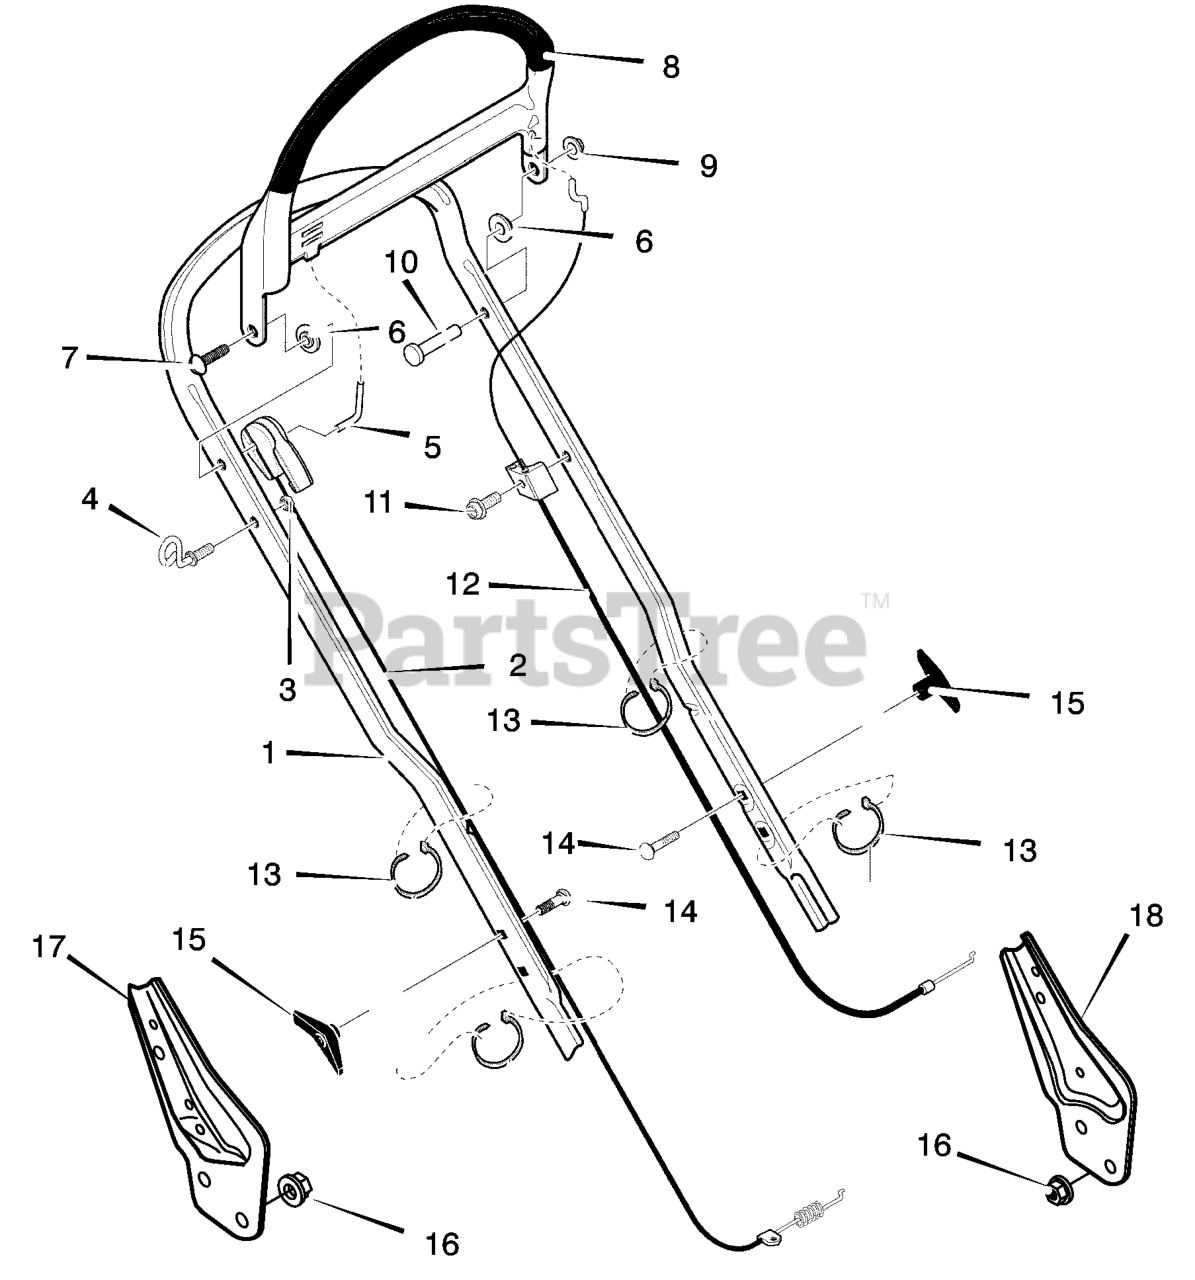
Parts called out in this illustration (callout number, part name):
1	Handle, Upper
2	Control, Drive
3	Locknut
4	Guide, Rope
5	Rod, Drive Link
8	Lever, Stop
9	Push-On Cap
10	Pin, Clevis
12	Cable, Stop
13	Strap, Tie
14	Bolt, Carriage
15	Wingnut
16	Nut
17	Bracket, Right Handle
18	Bracket, Left Handle
